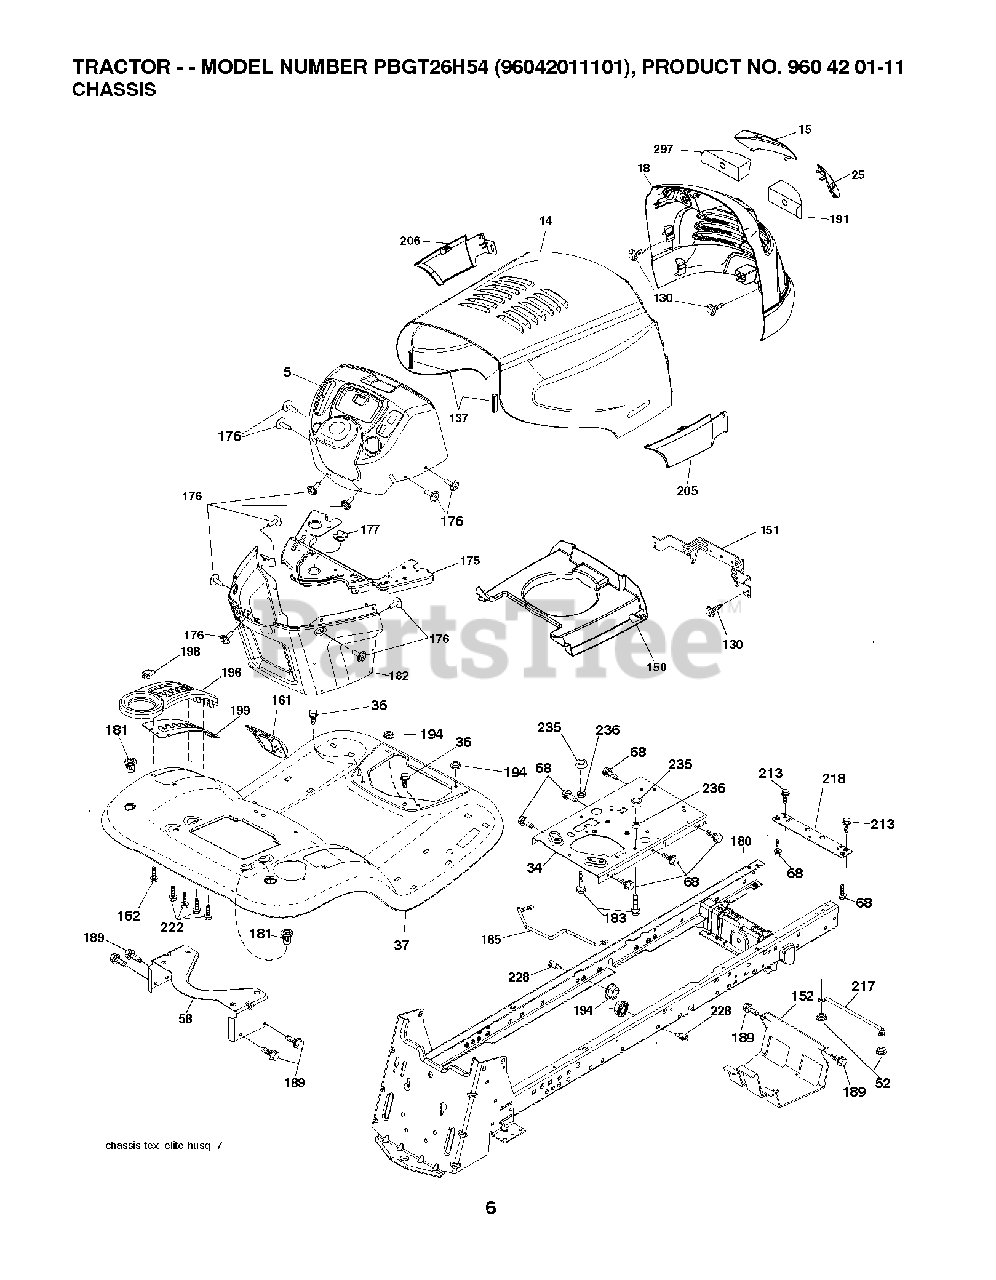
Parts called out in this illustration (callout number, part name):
14	HOOD.PNT.ELITE.TVENT.SVENT.SSK
18	GRILLE.ELITE HUSQ.BLACK.DL.
34	PLATE.ENGINE.WELDED.CHASSIS
36	SCREW 5/16"
52	LOCKNUT
58	BRKT.SUPPORT.FNDR/TANK
68	SCREW LT
130	SCREW.#10 X 0.750.BOS (2 2)
137	BUMPER.HOOD.LARGE.1.75"
150	AIR DUCT
151	BRACKET PIVOT
152	SHIELD.BROWNING.W/TEX
161	CONSOLE.FUEL.WINDOW.STGT.BLACK
162	SCREW.HI-LO.CONSOLE
165	SUPPORT.TANK.REAR.W/TEX
175	CROSSMEMBER.LT
176	SCREW.#10-24X5/8.RN.QU
177	BUSHING,STEERING
180	CHASSIS.GT.SLOPED.DRAWBAR.
181	FEND/FTRST.PCH.CPH.NFW
182	DASH.LOWER.LT.CCS
183	BOLT.5/16-18X1-1/4 FULL THD
189	SCREW
191	INSERT.REFLECTIVE.RH.
194	NUT LOCK HEX FLANGE 5/16-18
198	INDICATOR.DECK.LIFT.RED
199	PLATE DECK LIFT
205	SKIRT.SIDE.RH.ELITE.HUSQ.428
206	SKIRT.SIDE.LH.ELITE.HUSQ.BLACK
213	BOLT
217	ROD.PIVOT.HOOD
218	X-PIECE.HOOD.STOP.NON/
222	SCREW.1/4-20X5/8
228	STUD.FASTNER.W/ANTI-ROTATE
235	SPACER FENDER
236	NUT.CENTERLOCK.5/16-
297	INSERT LENS
